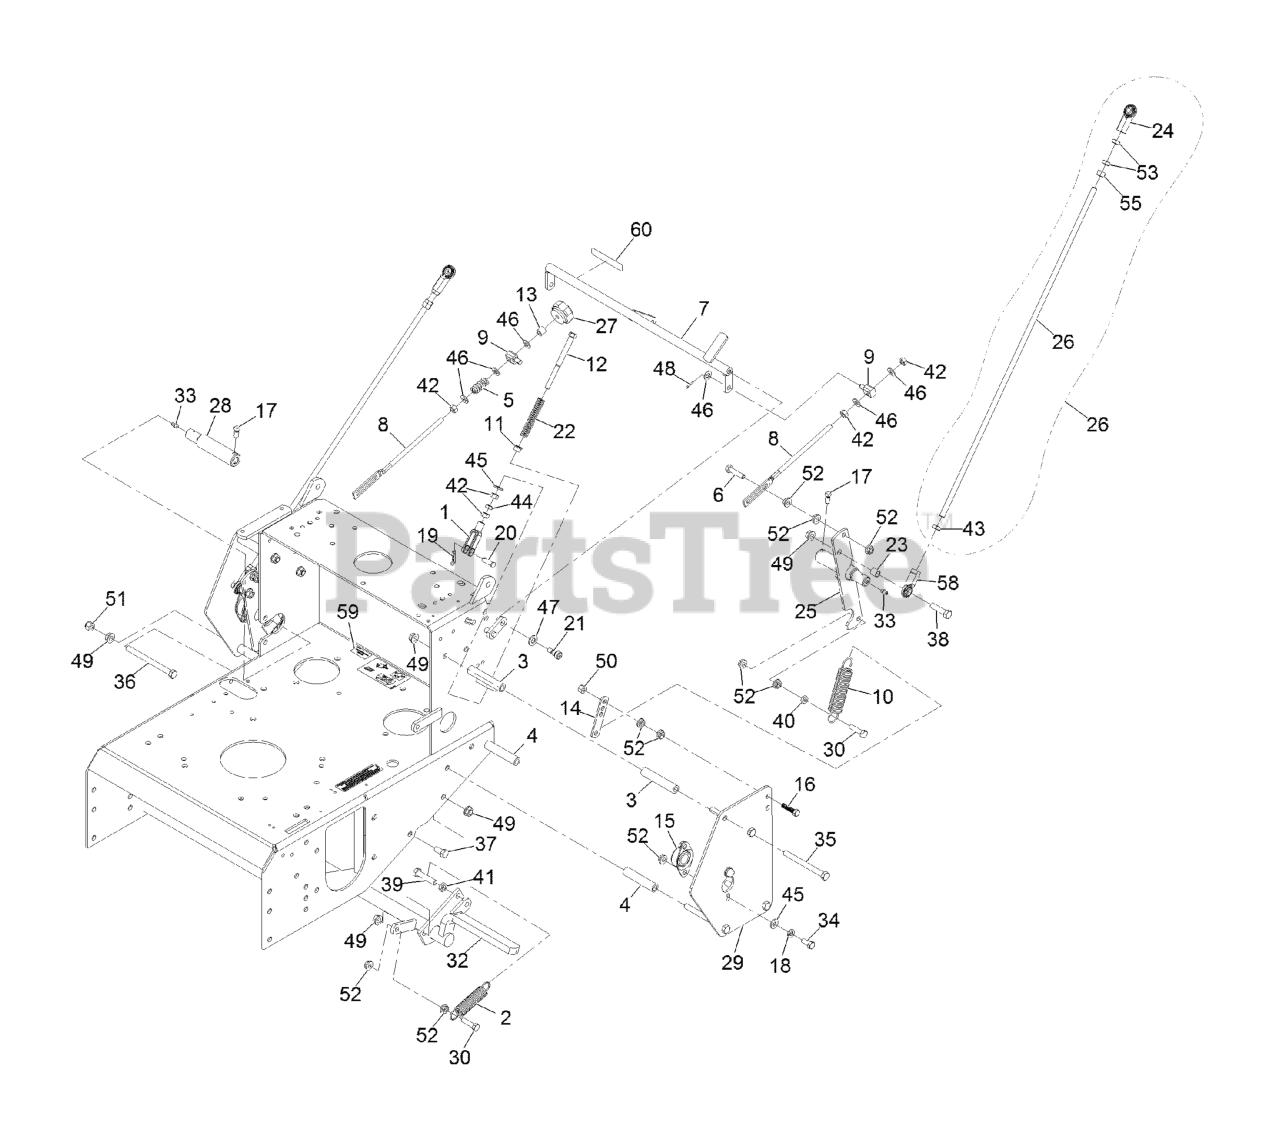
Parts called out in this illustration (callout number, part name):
1	YOKE-ADJUSTABLE
2	SPRING-IDLER
3	SPACER-SHIELD
4	SPACER-SHIELD
5	SPRING-COMPRESSION
6	SCREW-HH
7	CRANK-CONTROL, SPEED
8	LINK-CONTROL, SPEED
9	SWIVEL-ADJUSTABLE, SHORT
10	SPRING-EXTENSION
11	BUSHING-FLANGED
12	BOLT-RETURN, NEUTRAL
14	TAB-SPRING, EXTENSION
15	BEARING-FLANGE, SIDE
16	BOLT-TAP, HH
17	SCREW-SET
18	WASHER-LOCK
19	PIN-COTTER
20	PIN-CLEVIS
21	SCREW-HSH
22	SPRING,COMPRESSION (NEUT)
23	SPACER-TUBE, PUMP LINK
24	JOINT-BALL, END
25	SHAFT-CONTROL, LH
26	LINKAGE,DRIVE (PLT)
26	DRIVE LINK ASM
27	KNOB-TRACKING
28	SHAFT-CONTROL, RH
29	SHIELD-CONTROL
30	SCREW-HH, SPECIAL
33	FITTING-GREASE
34	SCREW-HH
35	SCREW-HH
36	SCREW-HH
37	SCREW-HH
38	SCREW-HH
39	SCREW-HH
40	NUT-JAM
41	NUT-JAM
42	NUT-HEX
43	NUT-HEX JAM, LH
44	NUT-JAM
45	WASHER-FLAT
46	WASHER-PLAIN
47	WASHER-FLAT
48	PIN-COTTER
49	NUT-HHF, WHIZ
50	NUT-LOCK, NI
51	NUT-LOCK, NI
53	NUT-HJ
55	NUT-HEX
58	JOINT-BALL END, LH
59	Decal-Patent Ttco.Com
60	DECAL-TRACKING ADJUSTMENT
